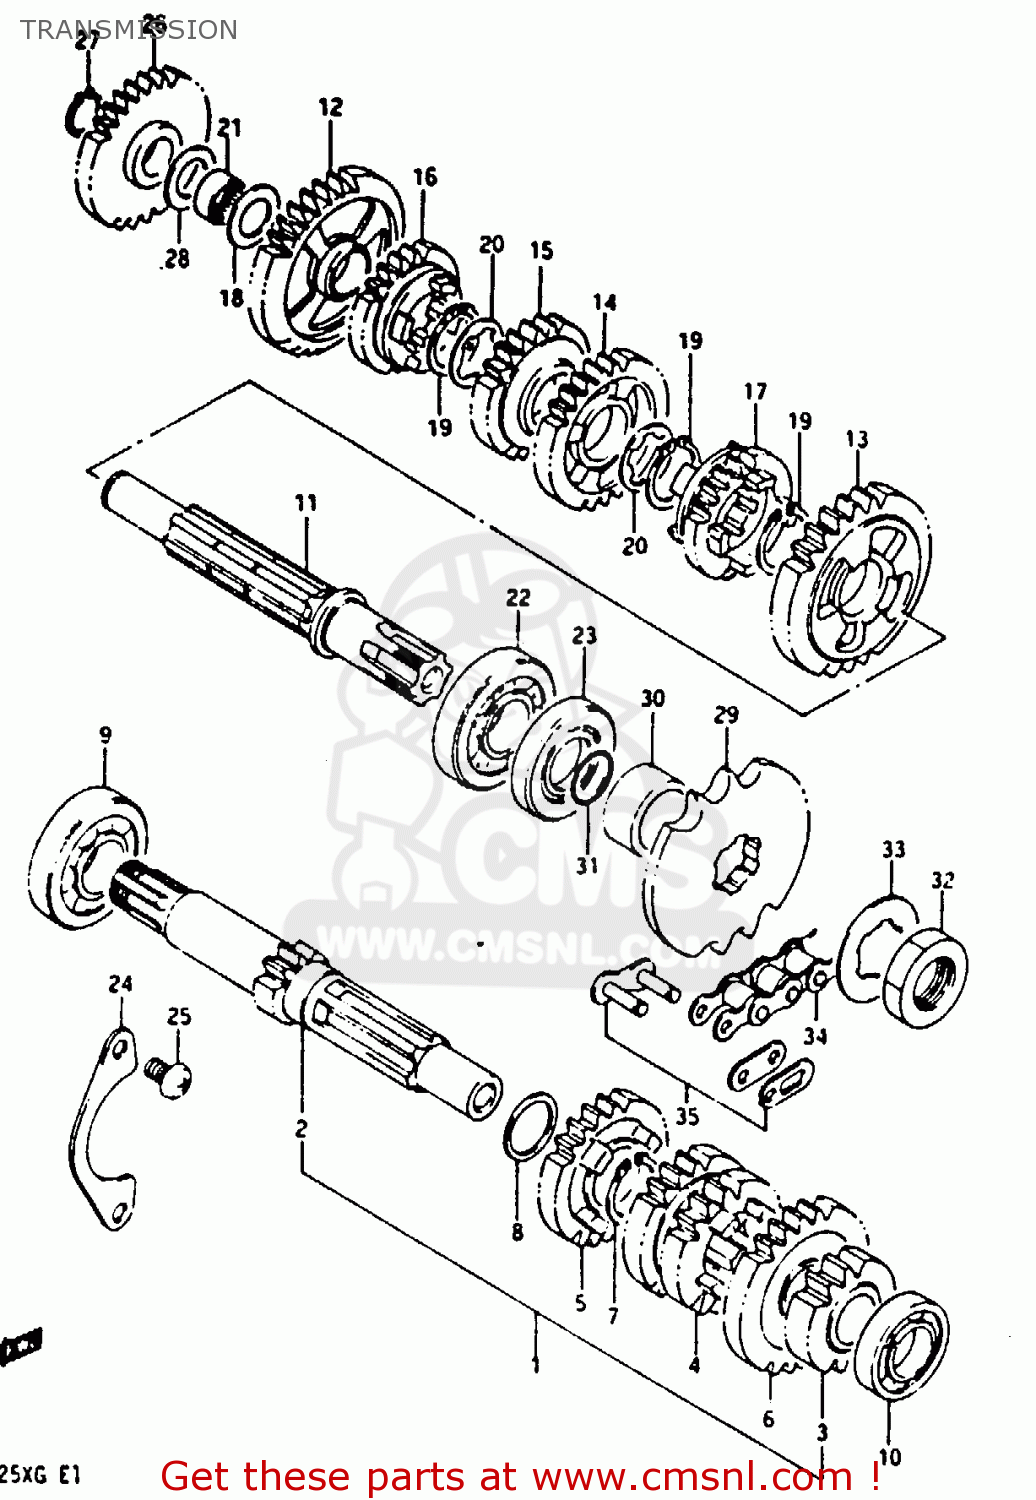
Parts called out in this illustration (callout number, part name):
1	COUNTERSHAFT ASSY
2	COUNTERSHAFT (NT:12)
3	GEAR, 2ND DRIVE (NT:16)
4	GEAR,3RD & 4TH DRIVE
5	GEAR, 5TH DRIVE (NT:21)
6	GEAR,6TH DRIVE
7	CIRCLIP
8	WASHER
9	BEARING
10	BEARING
11	DRIVESHAFT
12	GEAR,1ST DRIVEN
13	GEAR, 2ND DRIVEN (NT:29)
14	GEAR,3RD DRIVE
15	GEAR,4TH DRIVEN
16	GEAR, 5TH DRIVEN (NT:19)
17	GEAR,6TH DRIVEN
18	WASHER,THRUST
19	CIRCLIP
20	WASHER,LOCK
21	BEARING(15X33X12)
22	BEARING
23	SEAL,OIL(27X40X6)
24	RETAINER,CNTR SHAFT BEARING
25	SCREW 6X12
26	GEAR, KICK IDLE (NT:29)
27	CIRCLIP,15MM
28	WASHER
29	SPROCKET,ENGINE
30	SPACER(20X27X13.1)
31	O RING(D:1,ID:19.5)
32	NUT
33	WASHER,LOCK
34	CHAIN ASSEMBLY,DRIVE
35	JOINT SET,CHAIN
